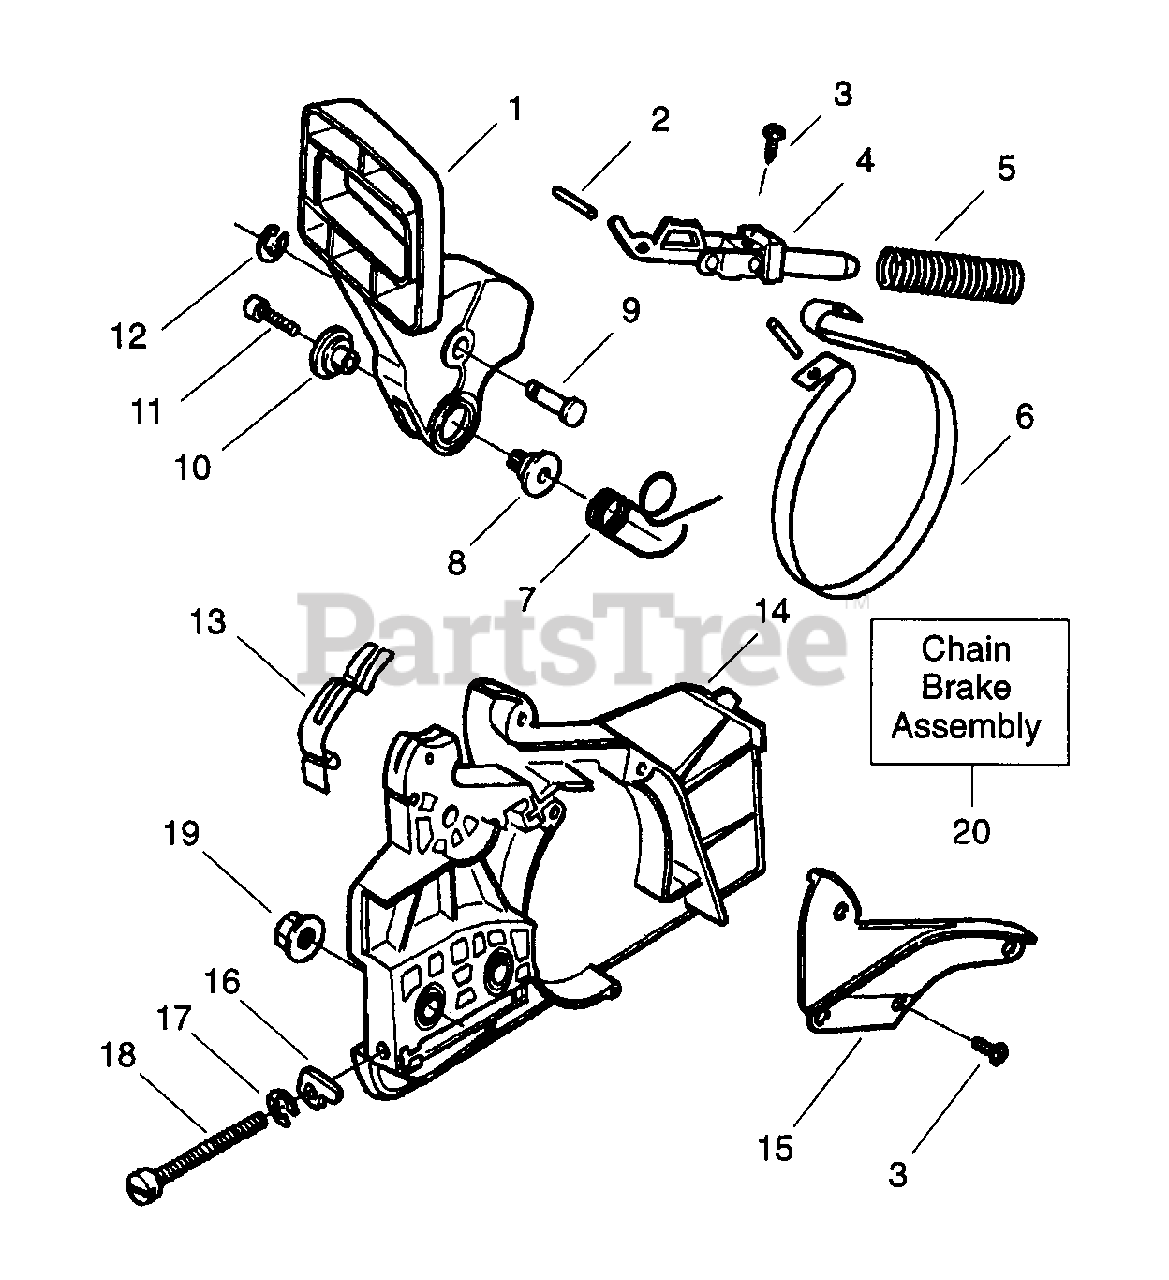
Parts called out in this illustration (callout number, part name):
1	HAND GUARD
3	SCREW
4	FRONT & REAR LINK ASSEMBLY NLA
5	%COMPRESSION SPRING
6	BRAKE BAND
7	SPRING,BRK HDL 36/41
8	SHAFT PIVOT
9	PIVOT PIN
10	SHAFT PIVOT
13	SPRING-POSITION
14	REPL BY 530 05 37-46
16	ADJUST PIN,BAR 36/41
18	BAR ADJUSTING SCREW
20	COVER
